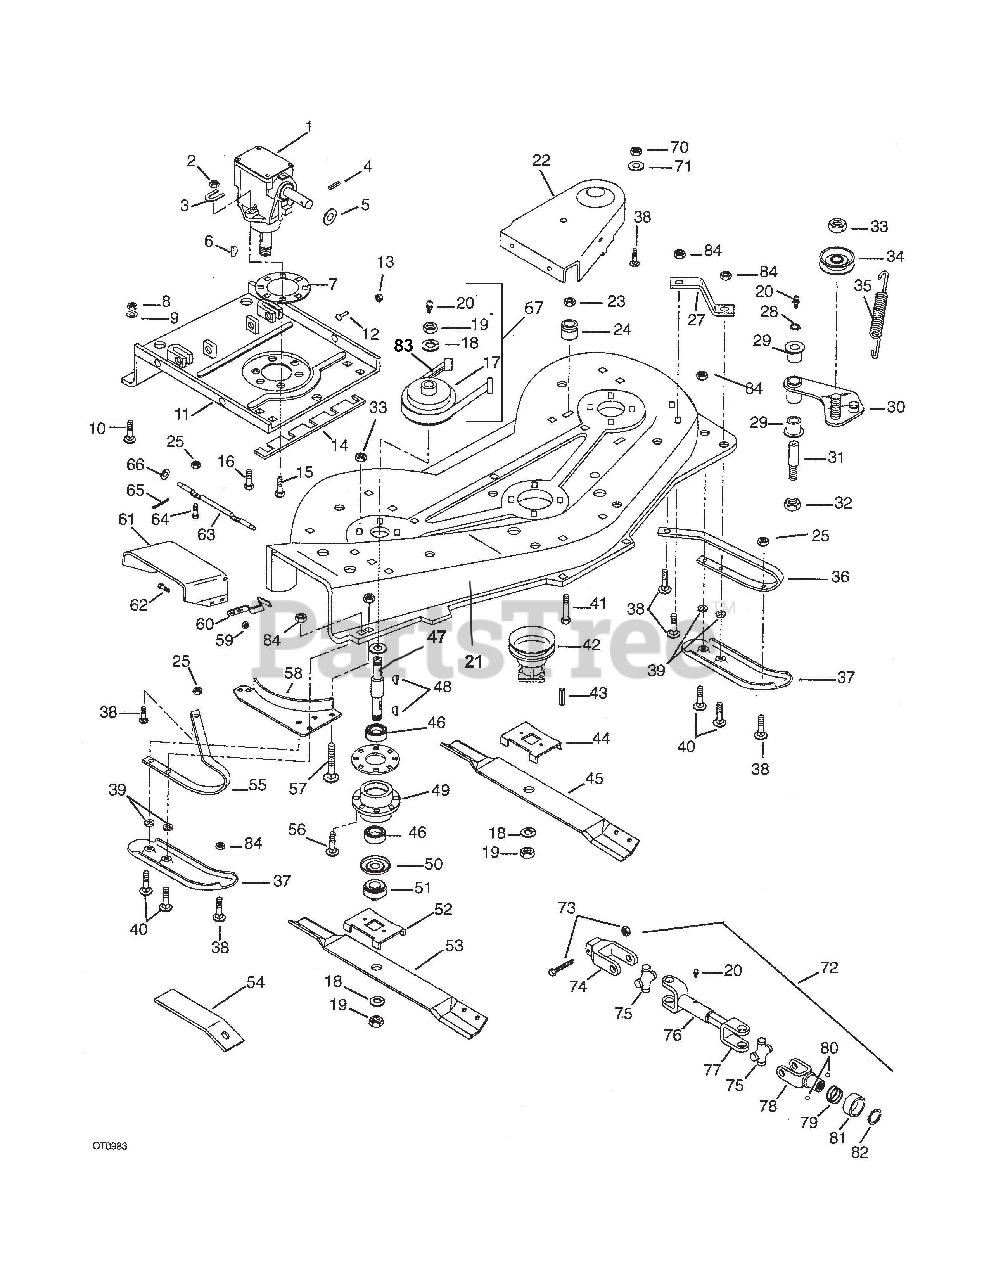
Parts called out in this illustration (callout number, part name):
1	MOWER GEARCASE 48" KIT
2	NUT-LOCKING-TIP .312-18
4	PIN-ROLL .125 X 1.00
5	WASHER-FLAT-STEEL .754 X 1.000 X .032
6	KEY-WOODRUF .25 X .75 X 5
8	NUT .50-13
9	WASHER-LOCKING .500 X .125
10	BOLT-ROUND HEAD SQUARE NECK .500-13 X 1.25 GRADE 5
11	MOUNTING PLATE
12	RIVET-STEEL RIGHT HAND .312 X .75
13	NUT-PUSH .312
15	SCREW-TAPPING .312-18 X 1.0
16	BOLT-HEX .31-18 X 1.25 GRADE 5
17	SPINDLE SHEAVE
18	WASHER-LOCKING .750 X .188
19	NUT-JAM .75-10
20	SPIN DRIVE ZERK FITTING
21	60 INCH MOWER DECK
22	BELT COVER LH 60"
22	BELT COVER RH 60"
23	NUT-LOCKING .375-16
24	SPRING ANCHOR
25	NUT-HEX .312-18
28	RING-RETAINING-EXTENSION .625 X .050
29	BUSHING-FLANGE .625 X .750 X .500 X .875
30	IDLER ARM
31	IDLER STUD
32	NUT-LOCKING-CENTER .50-13
33	NUT-LOCK-JAM-CENTER .375-16
34	IDLER-FLAT 2.75 X .38 DAYCO
35	SPRING-TENSION .121 X 1.06 X 6.5
36	SKID BAR LH
37	SKID BAR
38	BOLT-ROUND HEAD SQUARE NECK .31-18 X .75 GRADE 5
40	BOLT-ROUND HEAD SQUARE NECK .31-18 X 1.50
41	BOLT-HEX .38-16 X 1.75 GRADE 2
42	SHEAVE 1
43	PIN-GROOVE .188 X .75
44	BLADE TRAY
45	BLADE
46	BEARING-BALL .750 X 1.781 X .61
47	SPINDLE SHAFT W/ZERK
48	KEY-WOODRUF .188 X .62 X .25
49	SPINDLE HOUSING
50	BEARING SLINGER
51	RETAINER HUB
52	BLADE TRAY
53	MOWER BLADE 22 1/2"
55	SKID BAR RH
56	BOLT-ROUND HEAD SQUARE NECK .38-16 X 1.00
57	BOLT-ROUND HEAD SQUARE NECK .38-16 X 2.00
58	DEFELCTOR
59	NUT-LOCKING-CENTER .250-20
60	FLAT SPRING
61	CHUTE EXTENSION
62	BOLT-ROUND HEAD SQUARE NECK .25-20 X .50
63	HINGE PIN
64	BOLT-HEX .31-18 X .75 GRADE 5
65	PIN-COTTER .09 X .75
66	WASHER-FLAT-STEEL .406 X .81 X .065
67	SPINDLE ASSEMBLY
68	NUT-HEX .375-16
69	WASHER-LOCKING .375 X .115
70	NUT-LOCKING-CENTER .312-18
71	WASHER-FLAT-STEEL .344 X .688 X .065
72	PTO ASSEMBLY
73	SHEARBOLT & NUT ASSEMBLY
75	JOURNAL CROSS & BEARING ASSEMBLY
76	SLIP YOKE
77	YOKE & SHAFT
78	Q.D. YOKE
78	YOKE
79	SPRING
80	BALL .312
81	COLLAR
82	SNAP RING
82	SHAFT RETENTION KIT
84	NUT-LOCKING-TOP-FLANGE .31-18
85	BOLT-ROUND HEAD SQUARE NECK .38-16 X 1.00 GRADE 5
